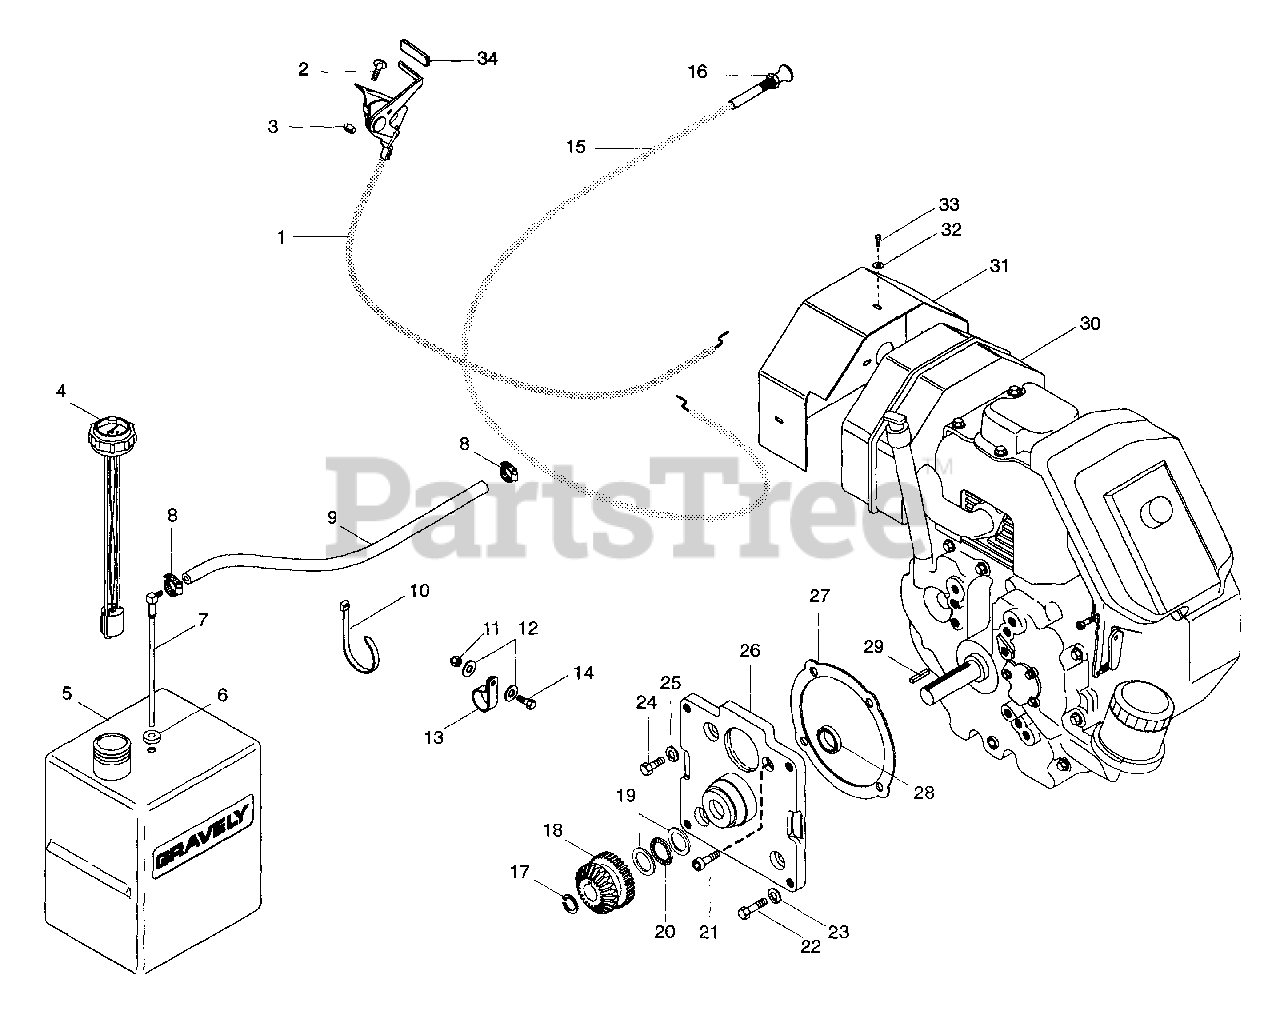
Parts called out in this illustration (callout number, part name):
1	Throttle Cable
2	Screw-Machine 10-32 x .50
3	Nut-Locking 10-32
4	Gauge, Fuel
5	Tank, Fuel
6	Bushing
7	Fitting, Tank
8	Hose-Clamp
9	Gas Line-Bulk
10	Tie Cable
11	Nut-Locking-Nylon .312-18 Grade 2
12	Washer-Flat-Steel .344 x .688 x .065
13	Cable Clamp
14	Bolt-Hex .31-18 x 1.00 Grade 5
15	Control, Choke
16	Nut-Jam .375-24
17	Ring-Retaining 1.249 x .050
18	Gear, Spur & Bevel
19	Washer-Thrust 1.125 x 1.750 x .123
20	Bearing-N-Thrust 1.84 x 1.127 x .078
21	Screw-Socket Head .44-14 x 1.00
22	Bolt-Hex .50-13 x 1.25 Grade S
23	Washer-Lock .50 Reg.
24	Bolt-Hex .44-14 x 1.125
25	Washer-Lock .438 x .133
26	Adapter, Engine
27	Gasket, Adapter
28	Seal 1.125 x 1.628 x .250
29	Key, Square .248 x 1.25 x .248
30	Engine, 14-HP Kohler, PS-1810
31	Weldment, Heat Shield
32	Washer-Flat-Steel .219 x .500 x .049
33	Screw-Drive 8-18 x .50
34	Knob
